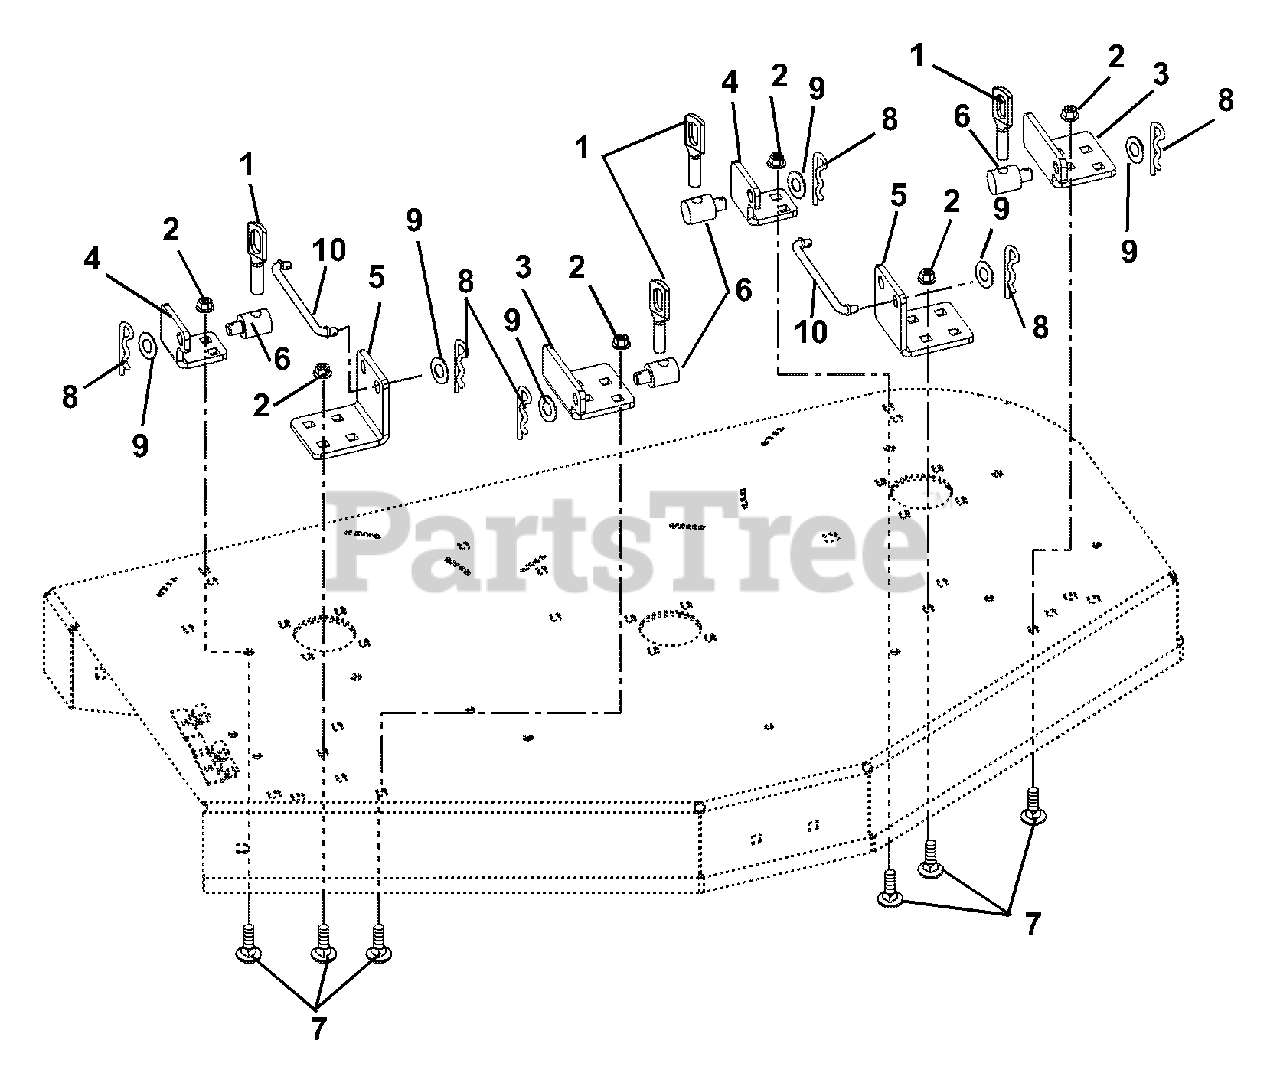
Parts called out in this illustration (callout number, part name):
1	Deck Link
2	Nut .38-16 Flange Nyloc
3	Bracket, Mount, Front
4	Bracket, Rear Mount
5	Bracket, Stabilizer
6	Trunnion
7	Bolt, Round Head Square Neck .38-16 x 1.00 Grade 5
8	Pin, Hair, External
9	Washer-Flat Steel .511 x 1.441 x .125
10	Rod, Drag Link
